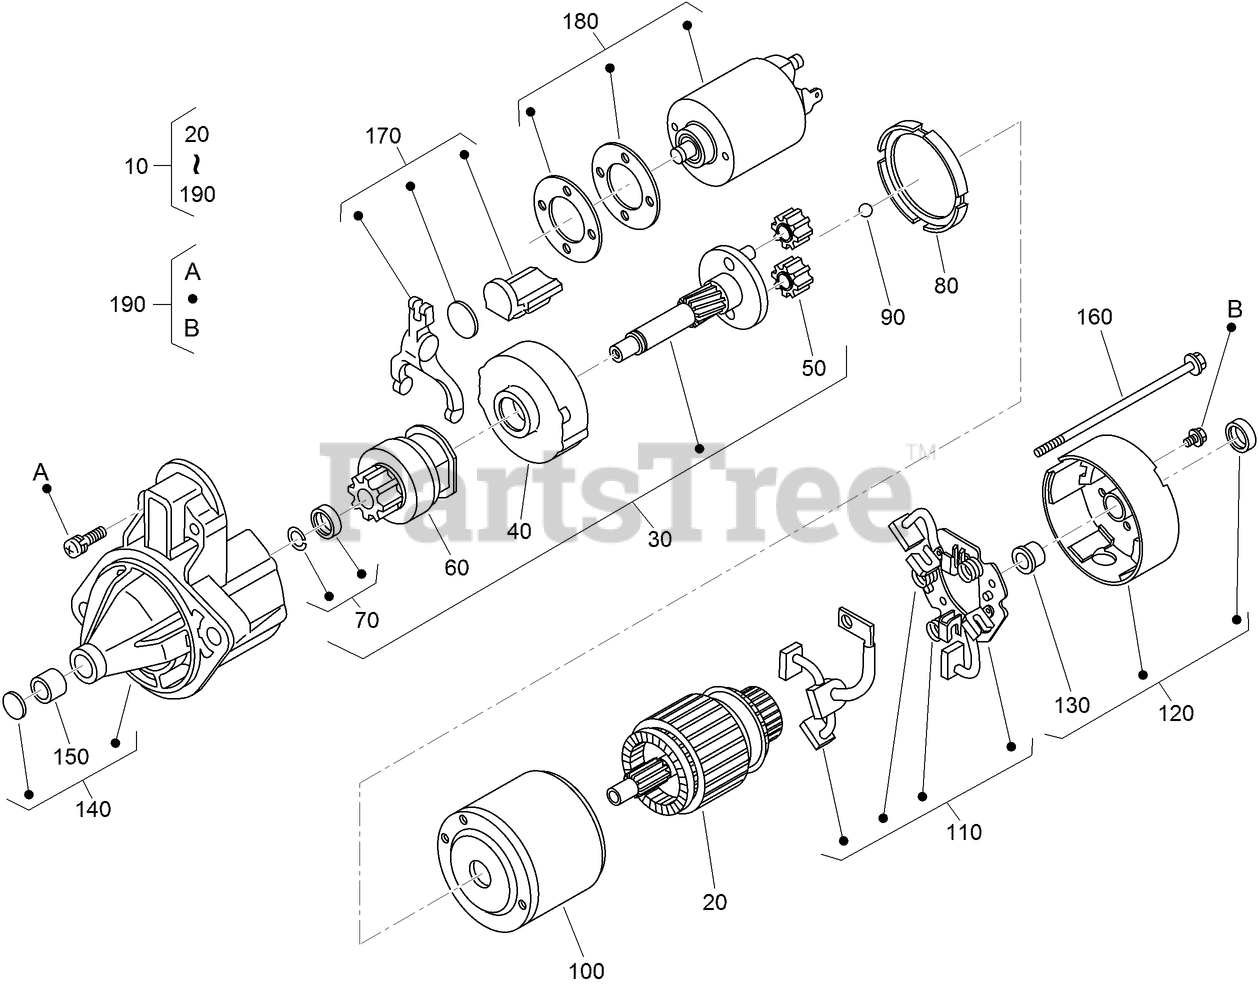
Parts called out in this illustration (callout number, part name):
20	ARMATURE
30	SHAFT ASM
40	GEAR-INTERNAL
50	GEAR-PLANETARY
60	CLUTCH-RUNNING, OVER
70	STOPPER
80	GASKET
110	BRUSH HOLDER ASM
120	REAR BRACKET ASM
130	BUSHING
140	FRONT BRACKET ASM
150	BUSHING
170	FORK LEVER ASM
190	SCREWS (SET OF 4)
